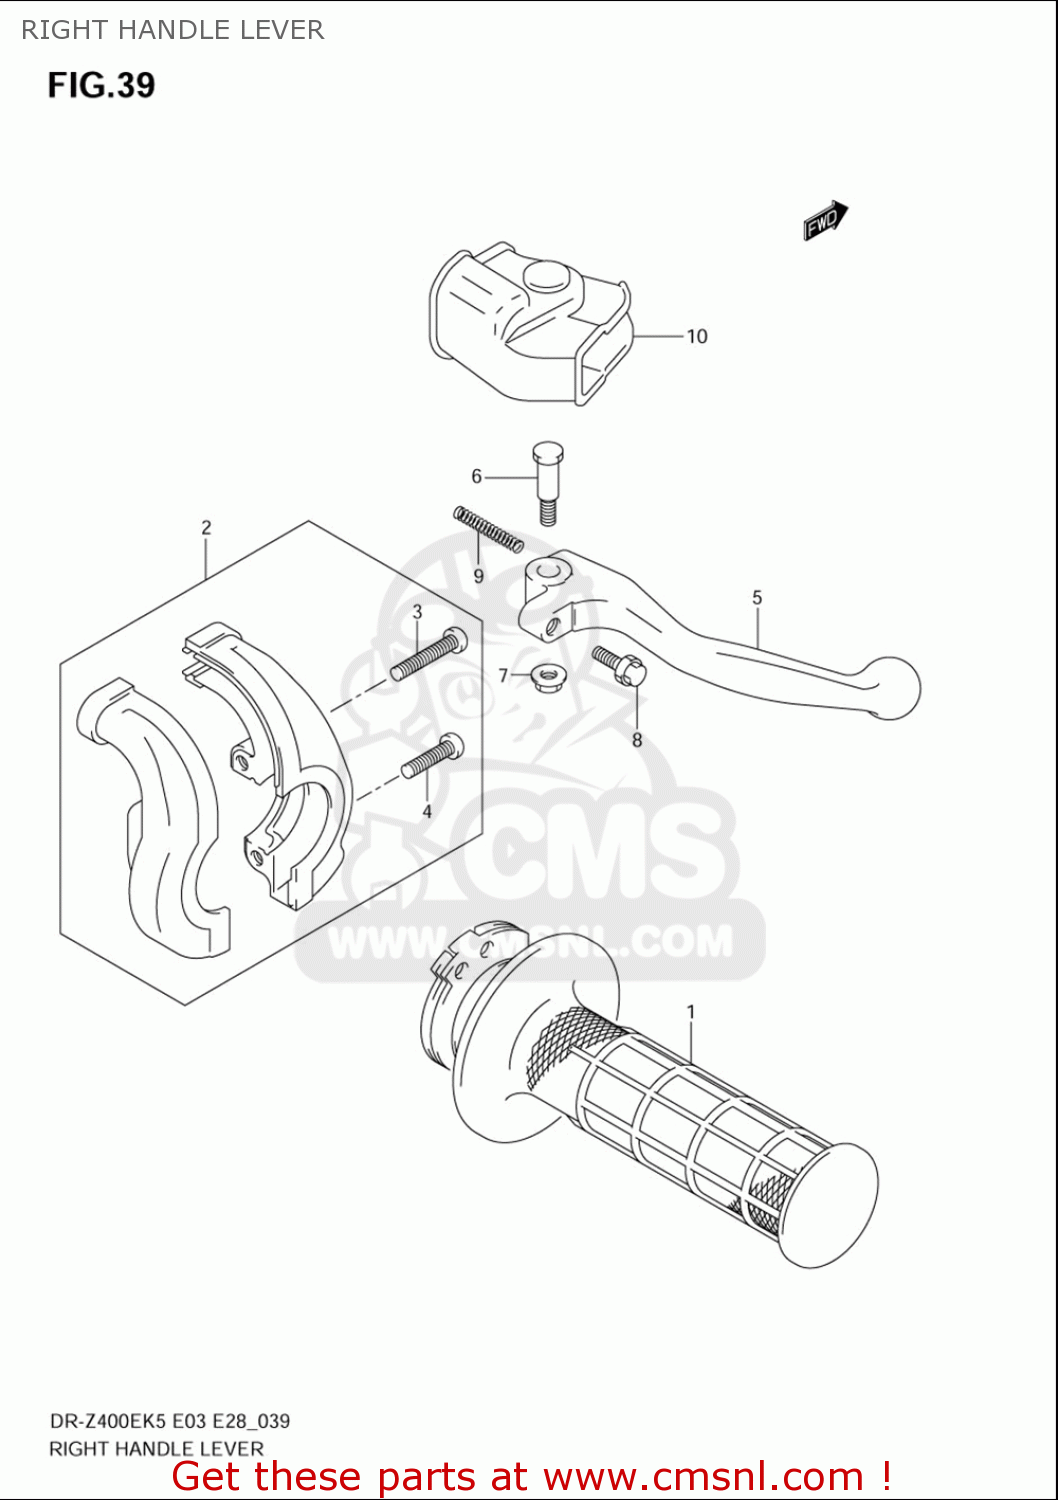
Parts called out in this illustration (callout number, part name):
1	GRIP,THROTTLE
2	CASE ASSY,THROTTLE
3	SCREW(5X25)
4	SCREW
5	LEVER,BRAKE
6	BOLT,BRAKE LEVER
7	NUT
8	BOLT,ADJUSTER
9	SPRING,RETURN
10	COVER,BRAKE LEVER
